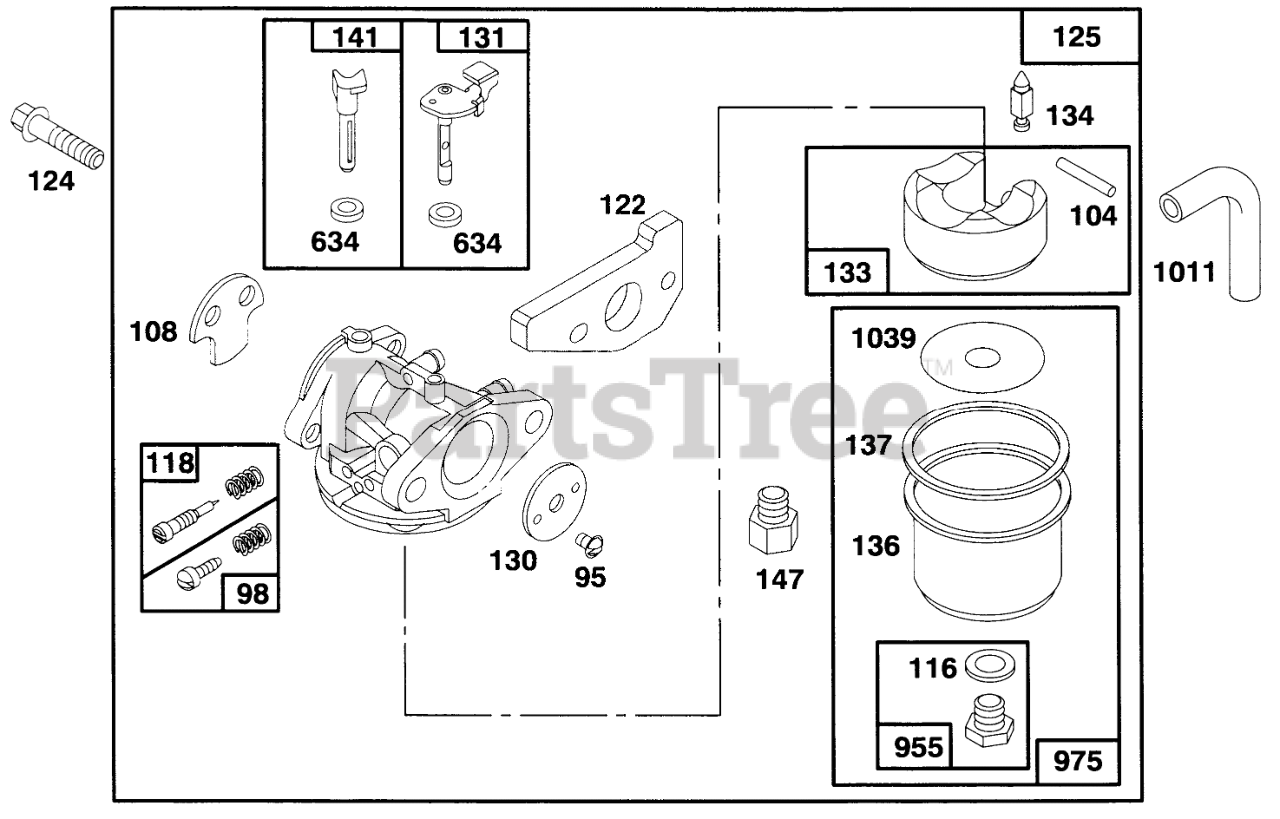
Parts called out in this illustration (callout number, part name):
95	SCREW - ROUND HEAD
98	IDLE ADJUSTING SCREW
104	FLOAT HINGE PIN
108	CHOKE VALVE
116	SEALING GASKET
118	VALVE KIT - NEEDLE
122	ADAPTER ASSEMBLY
124	HEX HEAD SCREW
125	CARBURETOR ASSEMBLY
130	THROTTLE VALVE
131	THROTTLE SHAFT
133	FLOAT-CARBURETOR
134	Valve-Inlet (Includes Seat)
136	FLOAT BOWL
137	FLOAT BOWL GASKET
141	CHOKE SHAFT
147	JET ADAPTER
634	SEAL WASHER
955	HEX HEAD SCREW
975	CARBURETOR BOWL ASM
1011	VENT TUBE
1039	FLOAT LIMITER
